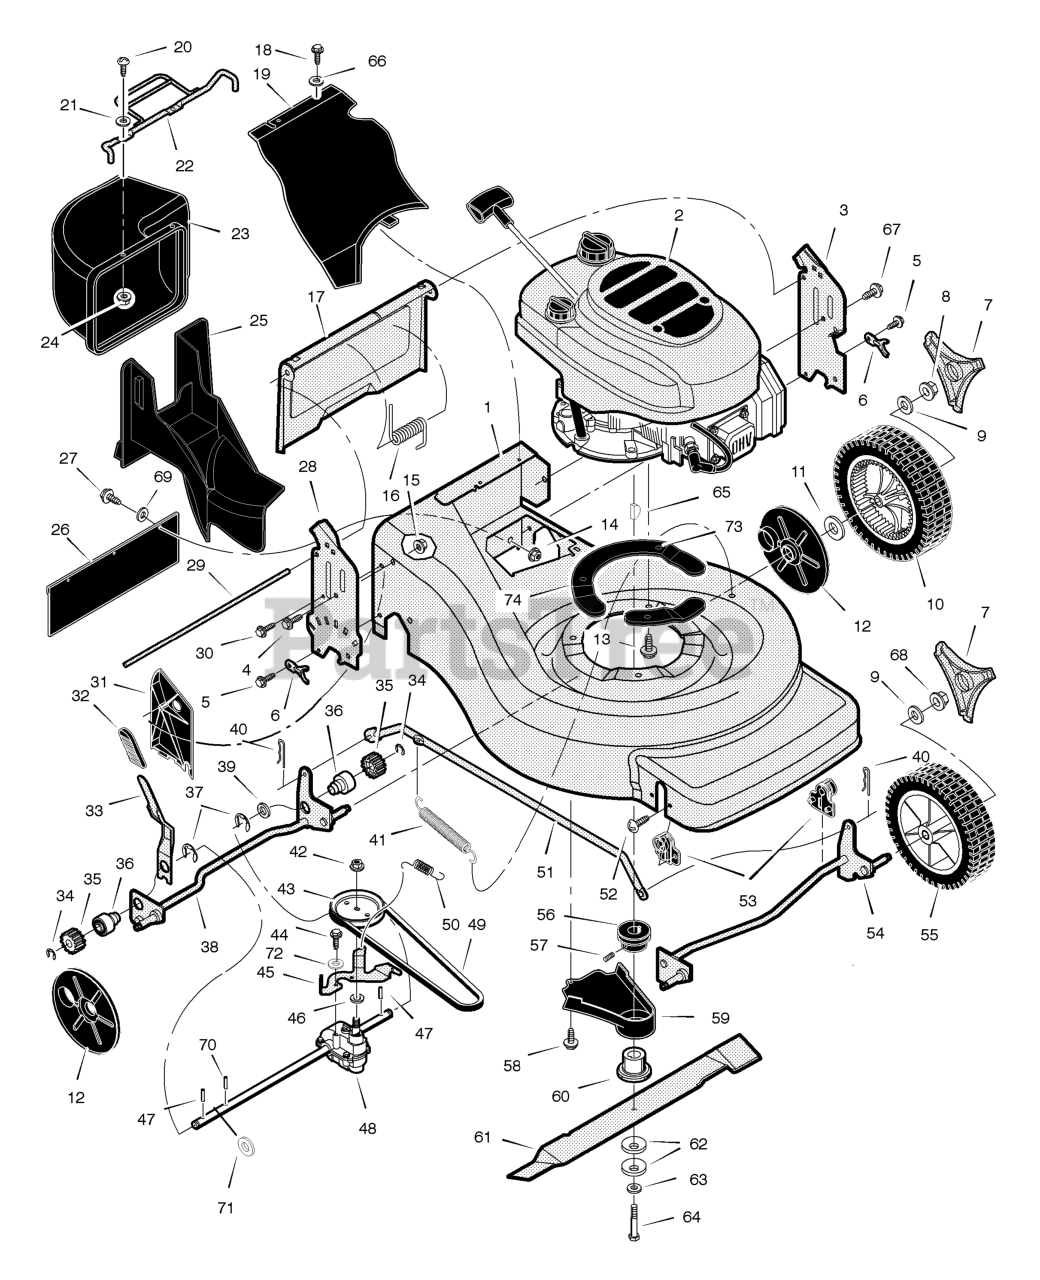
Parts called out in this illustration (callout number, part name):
2	Engine *
3	Bracket, Left Handle
6	Bracket, Crossbar Mount
8	Nut, Rear Axle 10X1.5
10	Wheel, Rear Drive
12	Dust Cover, Wheel
13	Screw, Engine Mount
16	Spring, Torsion
19	Cover, Upper Belt
20	Screw
21	Washer
22	Handle
23	Chute Assembly
24	Nut
25	Plug, Mulch
26	Guard, Rear
28	Bracket, Right Handle
29	Rod, Rear Door
31	Baffle, Rear Discharge
32	Grip, Height Adjust
33	Lever, Height Adjust
34	E-Ring, Rear Crossbar
35	Gear, Right Pinion
35	Gear, Left Pinion
36	Bearing & Sleeve Assembly
37	E-Ring, Transmission
38	Crossbar, Rear
39	Washer
40	Hairpin
41	Spring, Extension
43	Pulley, Transmission
45	Stop, Transmission Rotation
47	Pin, Drive
48	Transmission
50	Spring, Extension
51	Rod, Height Adjust
53	Block, Crossbar
54	Crossbar, Front
55	Wheel, Front
56	Pulley, Engine Crankshaft
57	Screw, Set (Engine Pulley)
58	Screw (Lower Belt Cover)
59	Guard, Lower Belt
60	Adapter, Blade
64	Bolt, Hex
65	Key, Woodruff No.5
68	Nut, Front Axle 10x1.5
70	Pin, Spring
73	Bracket, Engine Mount
74	Bracket, Engine Mount
